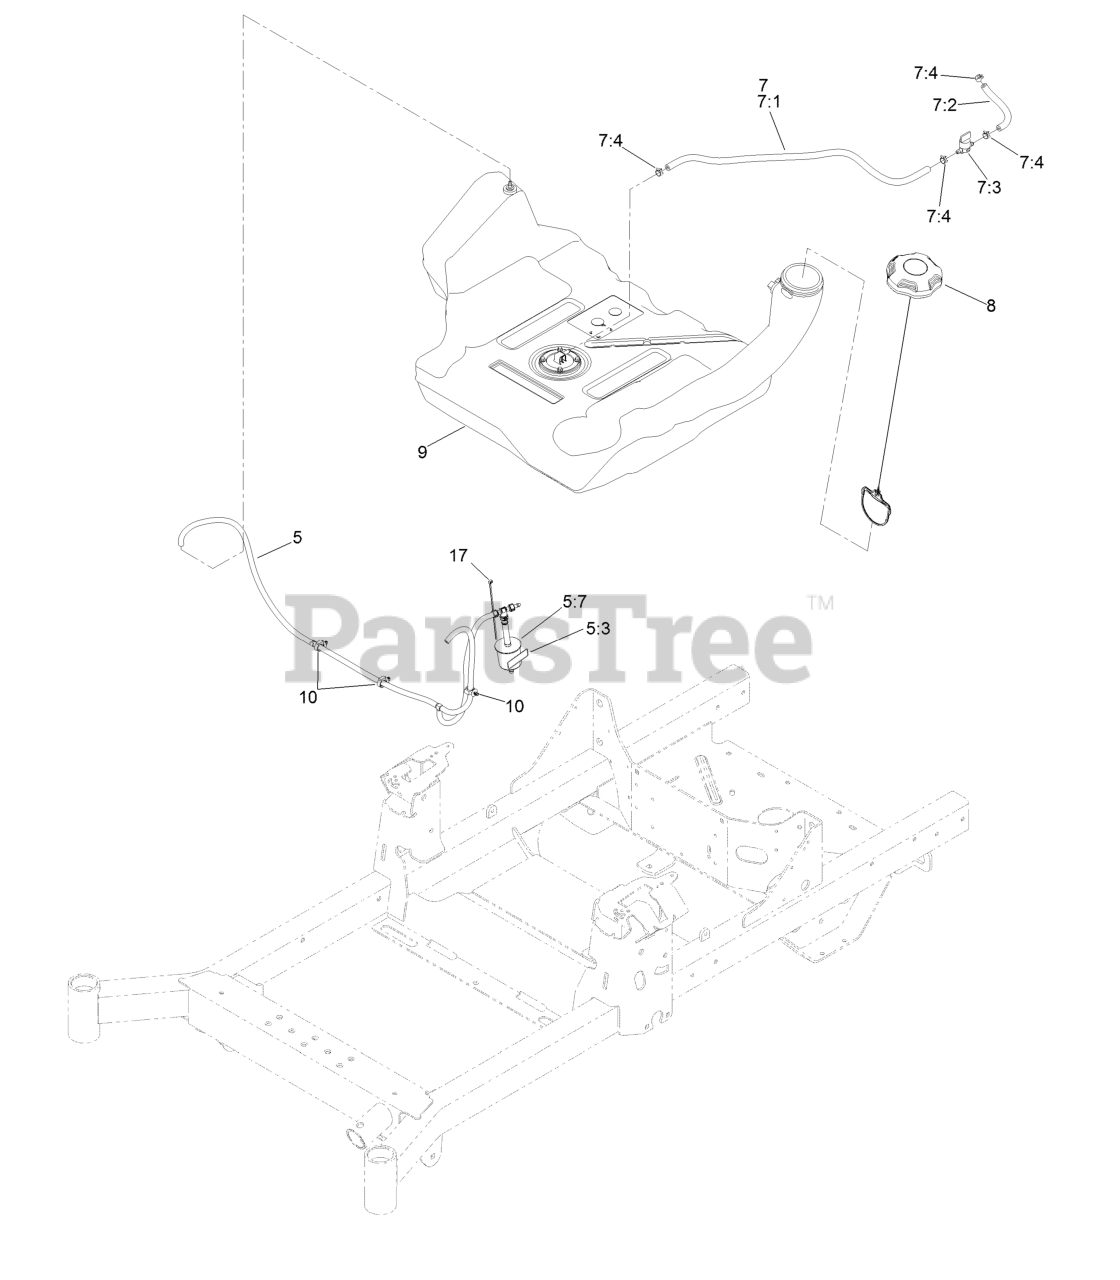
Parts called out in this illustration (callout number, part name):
5	Vent Hose ASM
5:3	Decal-Filter, Emissions
5:7	Filter-Fuel
7	Fuel Hose ASM
7:1	Hose-Fuel
7:2	Hose-Fuel
7:3	Valve-Fuel
7:4	Clamp-Hose
8	Cap-Fuel
9	Tank-Fuel
17	Tie-Cable
